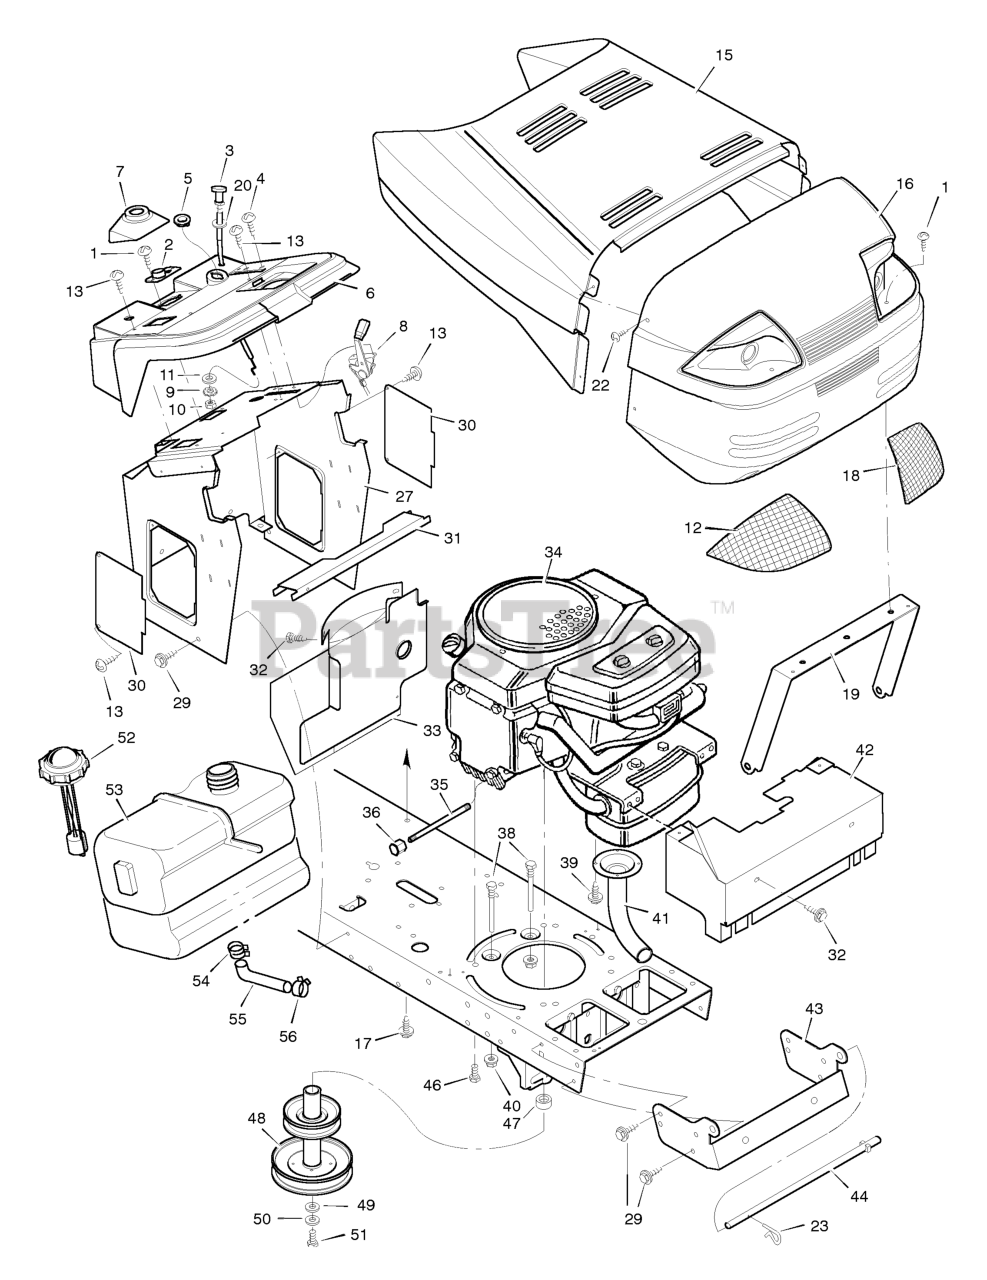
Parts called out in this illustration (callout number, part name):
2	Bearing, Steering Post
3	Cable, Choke
5	Bushing
7	Support, Bellows
8	Throttle Control
9	Lockwasher
10	Nut, Hex
11	Washer
12	Lens, Right
13	Screw
15	Hood
16	Grille
18	Lens, Left
19	Brace, Grille
20	Washer
23	Pin, Hair
27	Console Assembly
30	Panel, Side Access
31	Support, Fuel Tank
32	Screw
33	Baffle, Rear Heat
34	Engine *
35	Oil Drain Extension
36	Oil Drain Cap
38	Guide, Belt
40	Locknut, Flange
41	Pipe, Exhaust
42	Shield, Heat
43	Support, Grille
44	Rod, Pivot
46	Bolt, Hex
47	Spacer, Engine
48	Pulley Assembly, Stack
50	Lockwasher
51	Bolt, Hex
52	Cap, Fuel
53	Fuel Tank
54	Clamp, Hose
55	Fuel Line
56	Clamp, Hose
